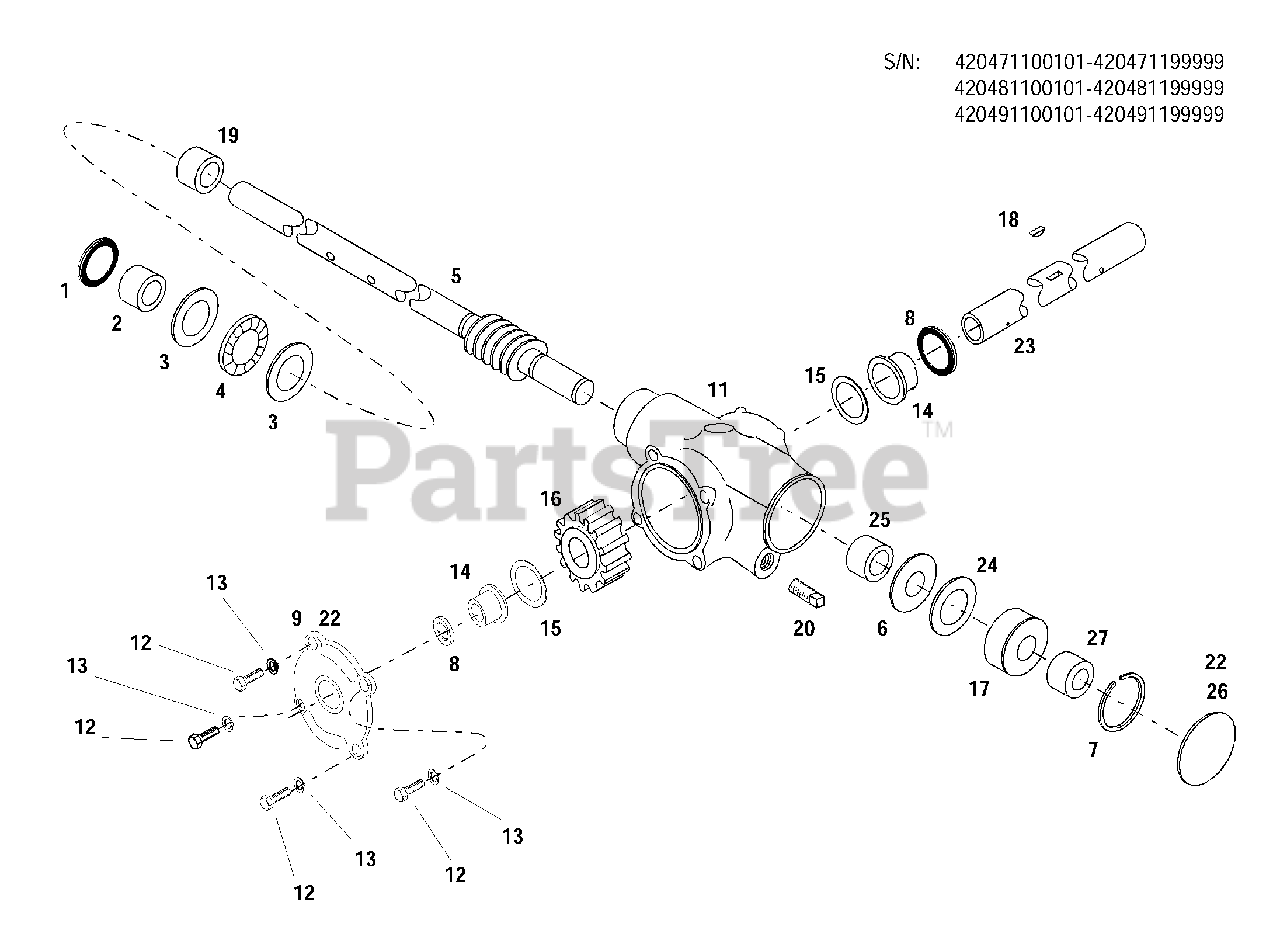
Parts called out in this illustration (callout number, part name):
1	Oil Seal
2	Needle Bearing
3	Thrust Race
4	Roller Thrust Bearing
5	Impeller Shaft
7	Internal Retaining Ring
8	Oil Seal
9	Flanged Cover
11	Gear Case
12	Hex-Head Cap Screw, 1/4-20 x 5/8
13	Lock Washer, 1/4
14	Flange Bearing
15	Thrust Race
16	Worm Gear, 20T
18	Woodruff Key, 1/4 x 7/8
19	Spacer
20	Square Head Plug, 1/4-18 NPT
22	Sealant
23	Auger Shaft
24	Thrust Race
26	Welch Plug
27	Needle Bearing
101	Gear Lube, EP 90, 8 Oz
